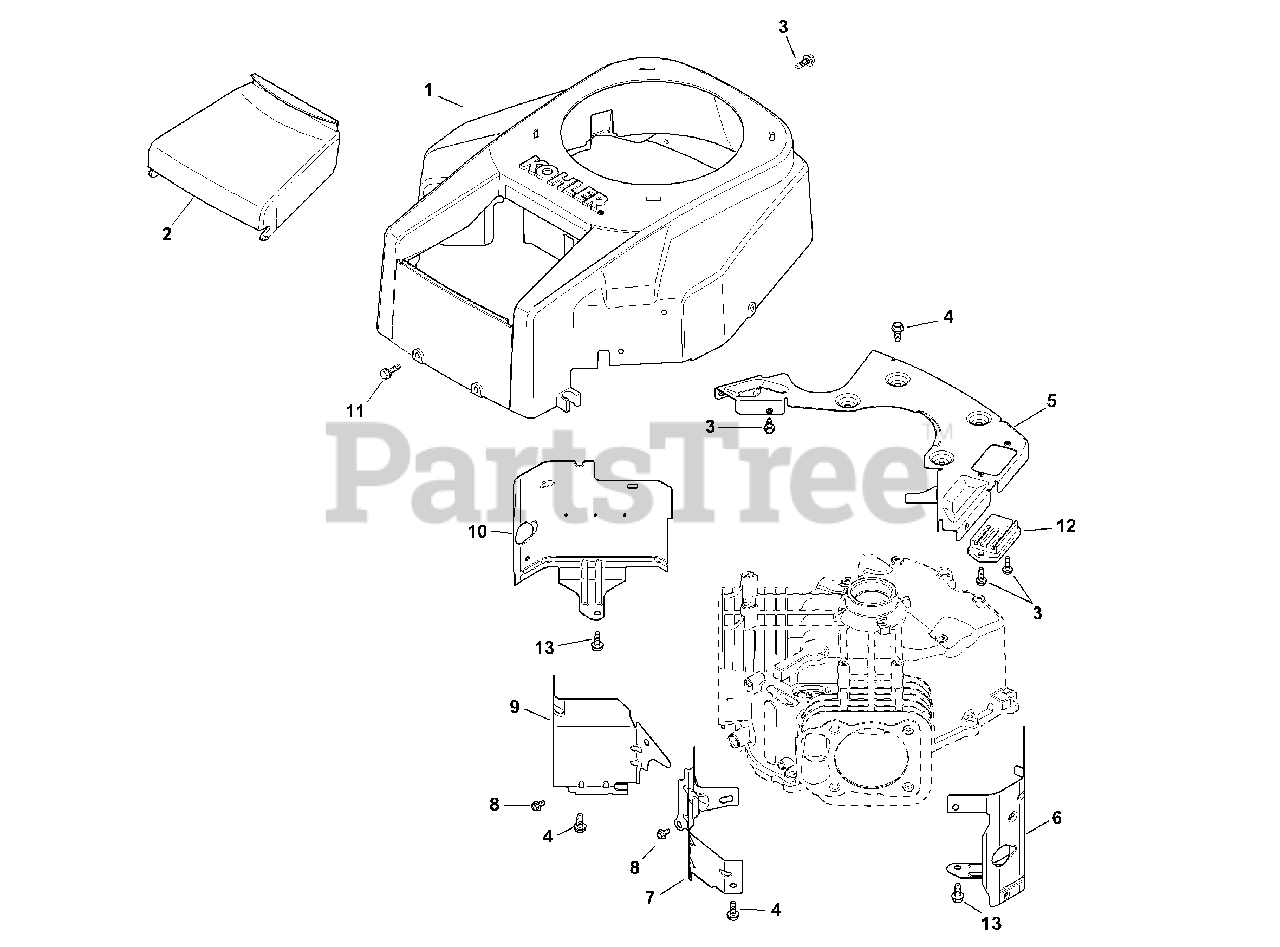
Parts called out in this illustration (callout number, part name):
1	Blower Housing Kit (Fixed Guard)
2	Air Cleaner Cover
3	Flange Screw, M5 x .8 x 16
4	Flange Screw, M6 x 1.0 x 16
5	Backing Plate Kit
6	Cylinder Barrel Baffle, #2 Side
7	Valley Baffle, #2 Cylinder
8	Flange Screw, M5 x .8 x 10
9	Valley Baffle, #1 Cylinder
10	Cylinder Barrel Baffle, #1 Side
11	Tap Screw, M6 x 1.7 x 18
12	Regulator/Rectifier
13	Screw, M6 x 1.0 x 10
